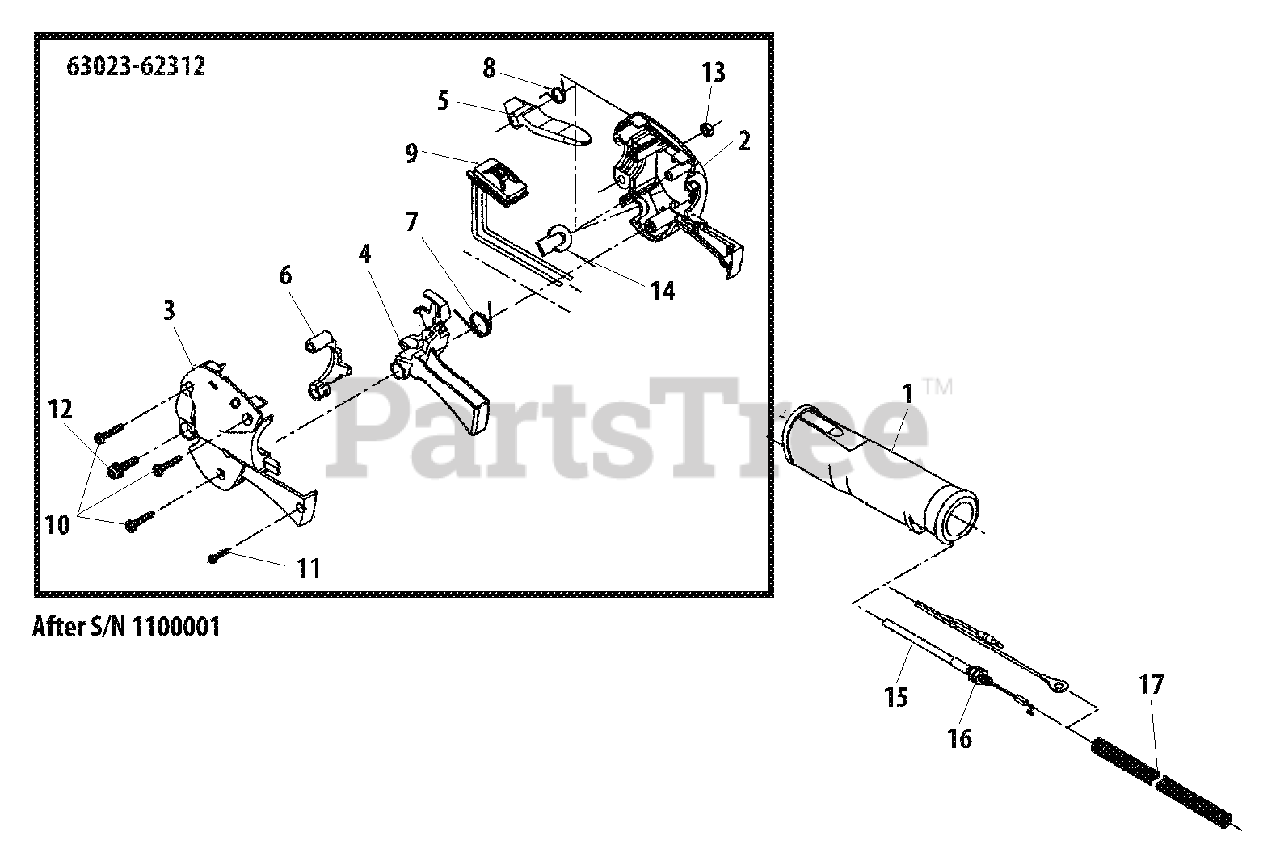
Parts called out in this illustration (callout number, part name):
1	GRIP
2	CONTROL HANDLE - RIGHT
3	CONTROL HANDLE - LEFT
4	TRIGGER, THROTTLE
5	LEVER, LOCK
6	LOCKOUT, THROTTLE
7	SPRING, THROTTLE RETURN
8	SPRING, THROTTLE LOCKOUT
9	SWITCH, ON-OFF
10	SCREW, TAPPING M4×20
11	SCREW, TAPPING 3×14
12	SCREW M5×20
13	NUT M5
14	PLUG
15	CABLE, THROTTLE
16	NUT M6
17	TUBE, PLASTIC PROTECTIVE
63023-62312	THROTTLE LEVER ASSY
